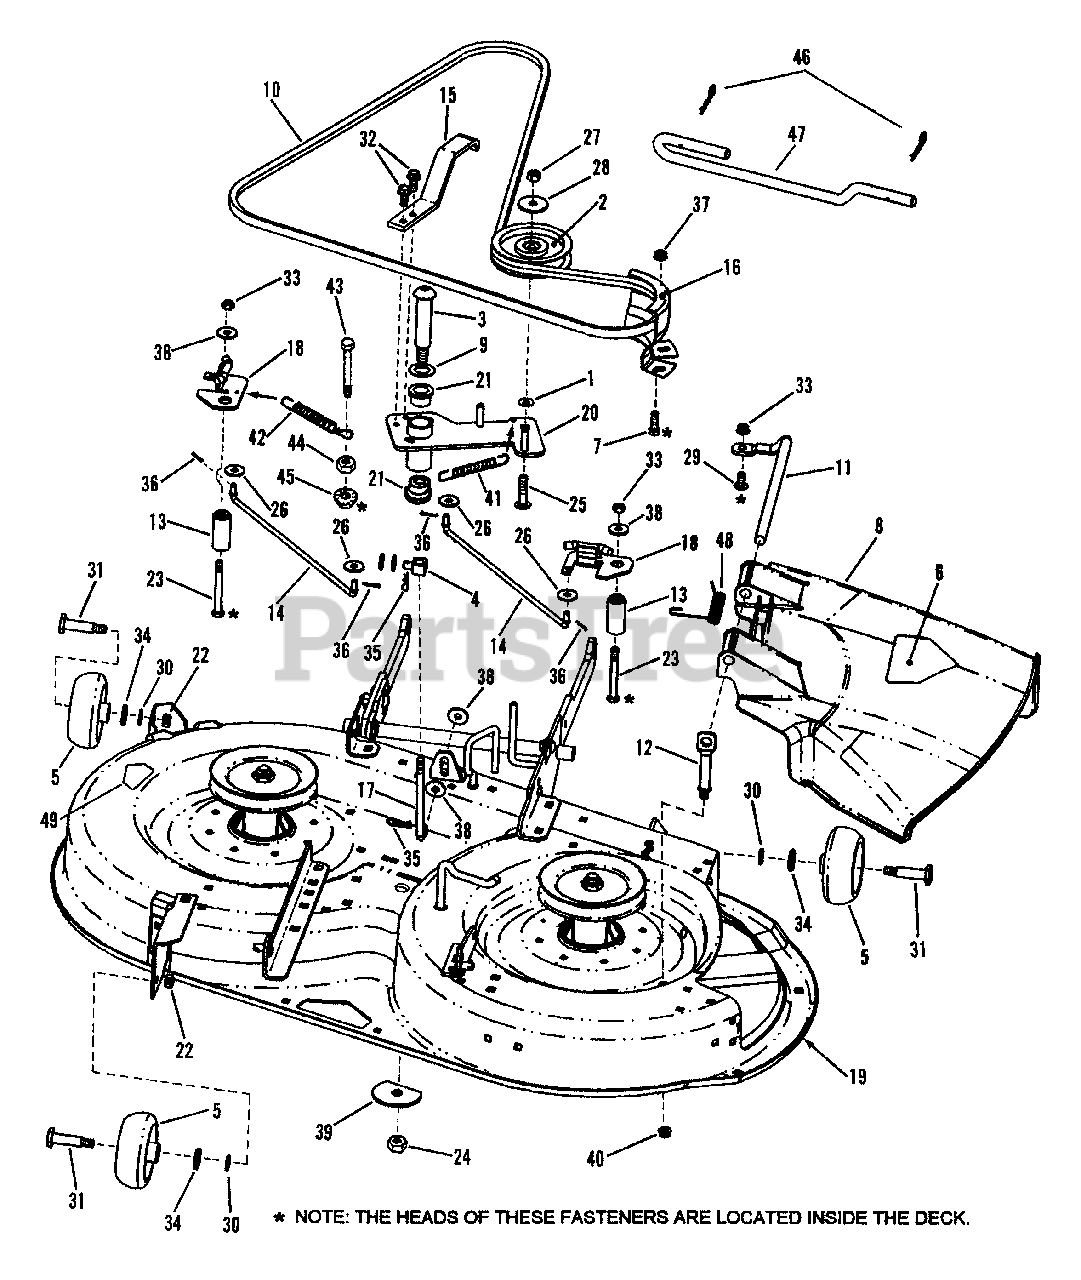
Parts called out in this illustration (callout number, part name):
1	RETAINER, 3/8" Bolt
2	IDLER, 4-1/8" Flat
3	BOLT, 3/4" Dia. X 3.01 Shoulder; 1/2-13 Thread
4	SWIVEL, Brake Link
5	WHEEL, Gage 38" Deck
6	DECAL, CPSC Cut Finger
7	SCREW, 5/16-18 x 1" Hex Head Cap, Grade 5
8	CHUTE, Discharge 38" Deck
9	WASHER, 3/4" I.D. Flat
10	BELT, 38" Deck Dual Spindle Brake
11	ROD, Pivot, Side Discharge
12	ROD, Mounting, Side Discharge
13	PIVOT, Dual Brake
14	BRAKE LINK, Dual Spindle Brake
15	LEVER, Engagement
16	GUARD, Belt, 38" Dual Spindle Brake
17	J-BOLT, 3/8-16 x 6-1/4"
18	ARM, Brake
19	ASSEMBLY, 38" Dual Brake Deck
20	ARM, Idler, Dual Brake
21	BEARING, 3/4" I.D.
22	NUT, 3/8-24 Hex Center Lock, Grade 5
23	SCREW, 5/16-18 x 3" Hex Head Cap, Gr. 5
24	NUT, 1/2-13 Hex Center Lock
25	BOLT, 3/8-16 x 1-3/4" Short Neck Carriage, Gr. 5
26	WASHER, 1/4" I.D. Flat
27	NUT, 3/8-16 Hex, Grade 5
28	WASHER, 13/32" I.D. Flat
29	BOLT, 5/16-18 x 3/4" Short Neck Carriage, Gr. 5
30	WASHER, 3/8" Flat
31	BOLT, 5/8" Dia. Shoulder, 3/8-24 Thread
32	SCREW, 5/16-18 x 3/4" Self-Tapping
33	NUT, 5/16-18 Hex Center Lock, Grade 5
34	WASHER, 1/2" I.D. Flat
35	PIN, #13 Hair
36	PIN, 3/32 x 3/4" Cotter
37	NUT, 5/16-18 Hex, Grade 5
38	WASHER, 11/32" I.D. Flat
39	WASHER, 1/2" I.D. x 2-1/2" O.D. Special "D"
40	NUT, 3/8-16 Hex Flange Lock
41	SPRING
42	SPRING, Extension
43	SCREW, 1/4-20 x 2-3/4" Hex Head Cap, Grade 5
44	NUT, 1/4-20 Hex, Grade 5
45	NUT, 1/4-20 Hex Flange Lock, Grade 5
46	HAIRPIN
47	PIN, Deck Hanger
48	SPRING, Side Discharge
49	DECK, 38 Inch
